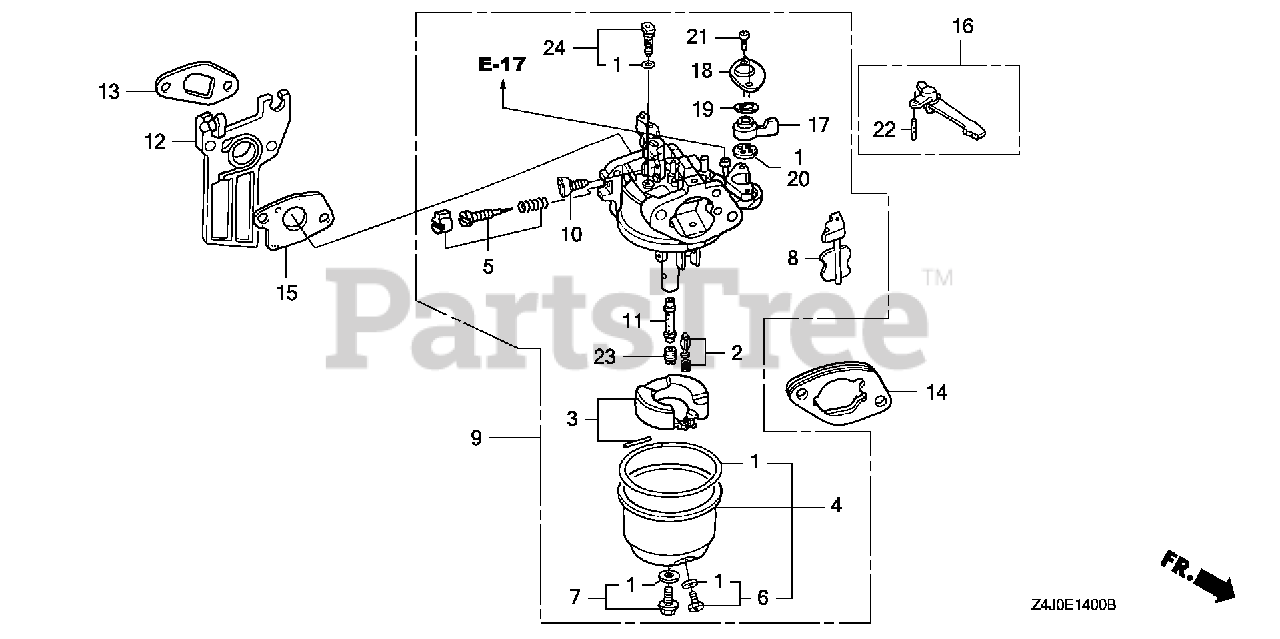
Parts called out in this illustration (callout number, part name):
1	GASKET SET
2	VALVE SET, FLOAT (SEAT NOT INCLUDED)
4	CHAMBER SET, FLOAT
5	SCREW SET, PILOT
6	SCREW SET, DRAIN
7	SCREW SET
9	CARBURETOR ASSY. (BE66E B)
10	SCREW, THROTTLE STOP
11	NOZZLE, MAIN
12	INSULATOR, CARBURETOR
13	GASKET, INSULATOR
14	SPACER, CARBURETOR
15	GASKET, CARBURETOR
16	LEVER, CHOKE (STD)
17	LEVER, PETCOCK
18	PLATE, LEVER SETTING
19	SPRING, PETCOCK LEVER
20	GASKET, PETCOCK
21	SCREW, PAN (3X6)
22	PIN, SPRING (2X12)
23	JET, MAIN (#65)
23	JET, MAIN (#68)
23	JET, MAIN (#70)
24	JET SET, PILOT (#35)
